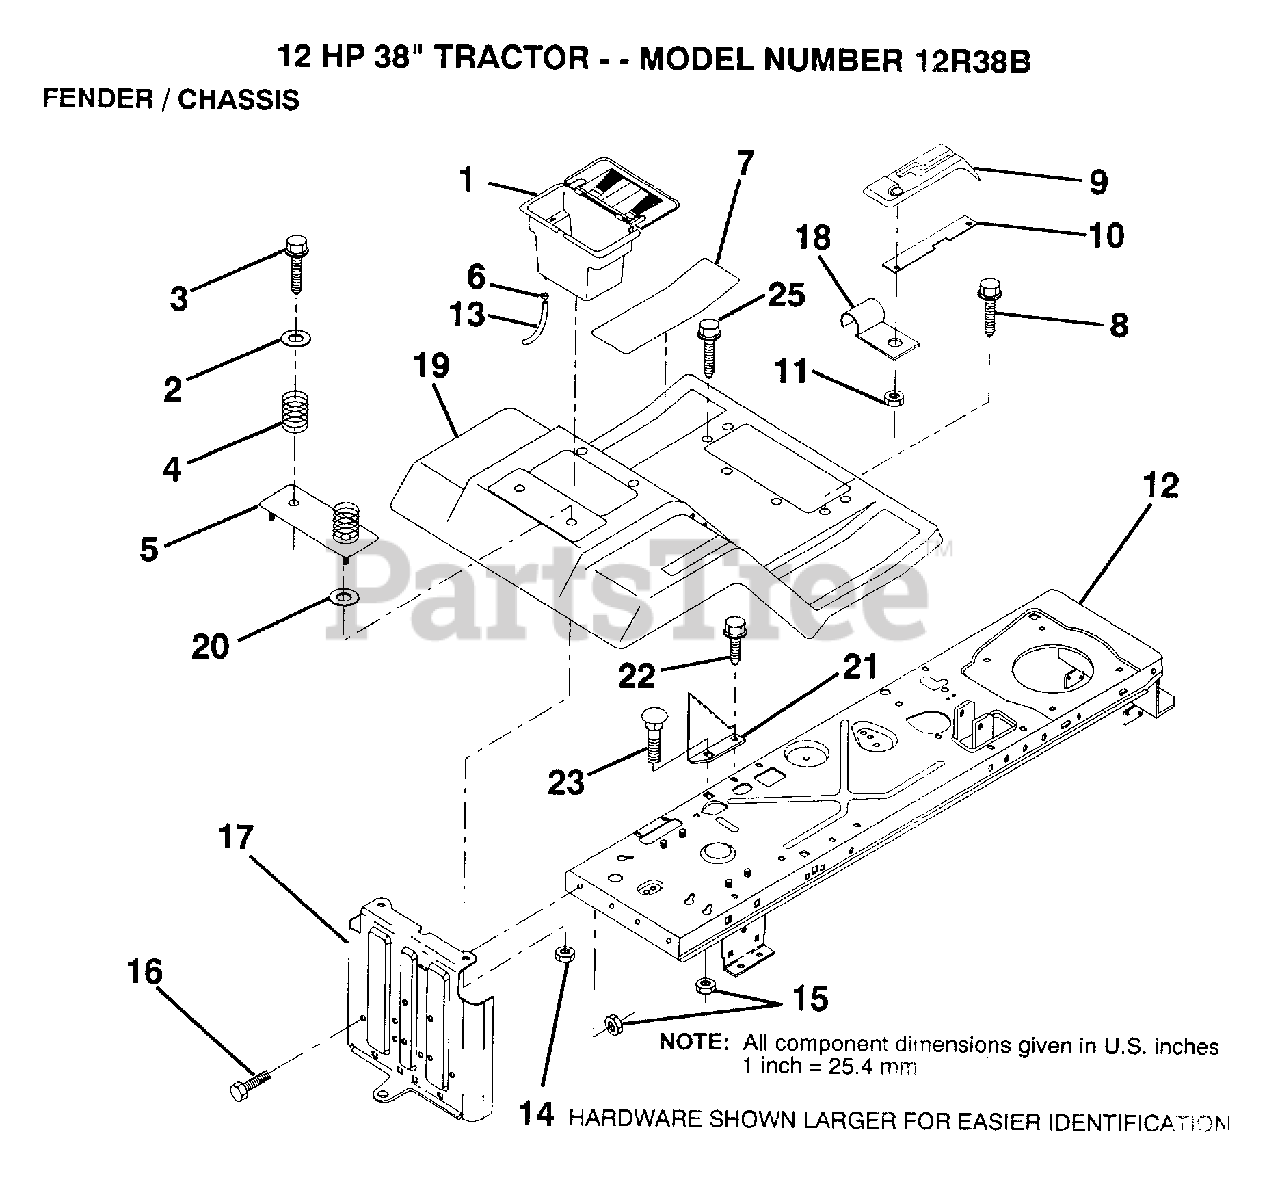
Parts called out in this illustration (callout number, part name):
2	WASHER
3	SCREW
4	SPRING COMPRESSIO
5	BTRY FENDER PLATE
6	HOSE CLAMP T
7	PAD FOOTREST
8	SCREW
10	"SHIFT LOCK, BAR"
11	NUT
13	TUBE T
14	NUT
16	BOLT
17	DRAWBAR
18	"CLIP,INSULATOR"
22	SCREW LT
25	SCREW TI
